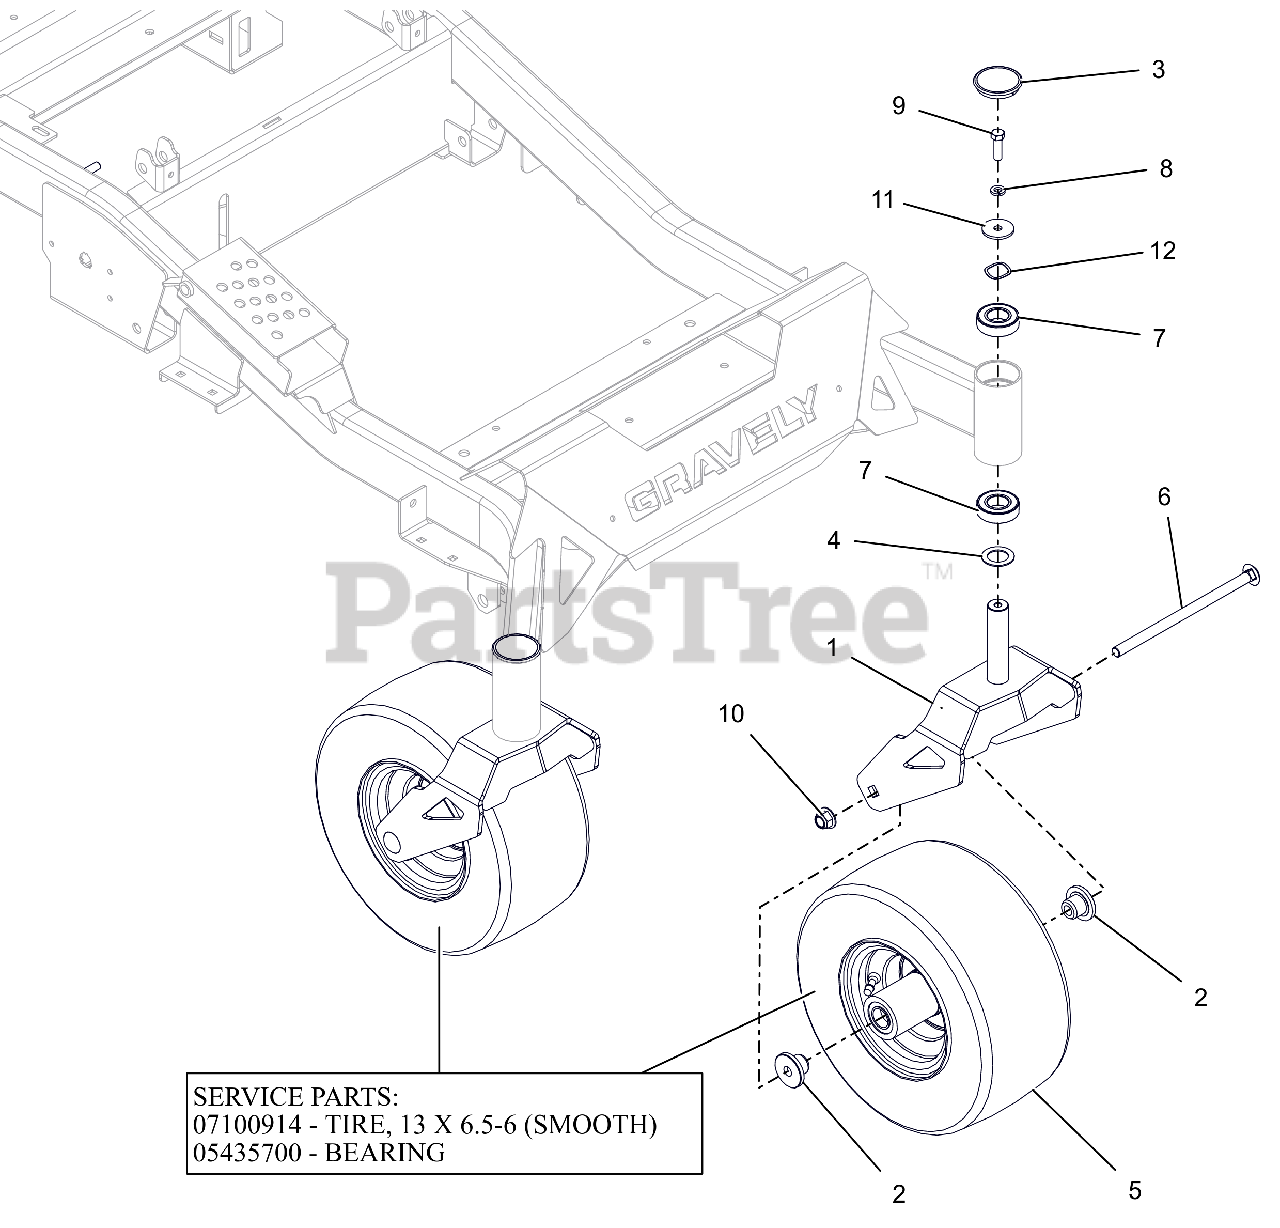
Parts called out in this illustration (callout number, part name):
1	WLDMT, HD CASTER FORK
2	SPACER, FRONT WHEEL
3	CAP, DUST
4	WSHR-HRD-THRS 1.007X1.542X.062
5	ASM, WHL/TIRE 13X6.50-6
5	TIRE, 13X6.50-6 SMOOTH
5	BRG, 25MM ID X 52MM OD X 15MM
6	BTL,RHSN .500-13 X 9 G5 ZCC
7	BRG,BALL 1.00X2.00X.563(1641)
8	WSHR, LK-HVY .375X.115 ZCC
9	BLT, HEX .38-16X1.25 G5 ZCC
10	NUT,NYL-FLG .50-13 GF ZCC
11	WSHR, FLT .380X1.50X.125 ZCC
12	WSHR-WAVE 1.0X1.25X.028 .145FH
